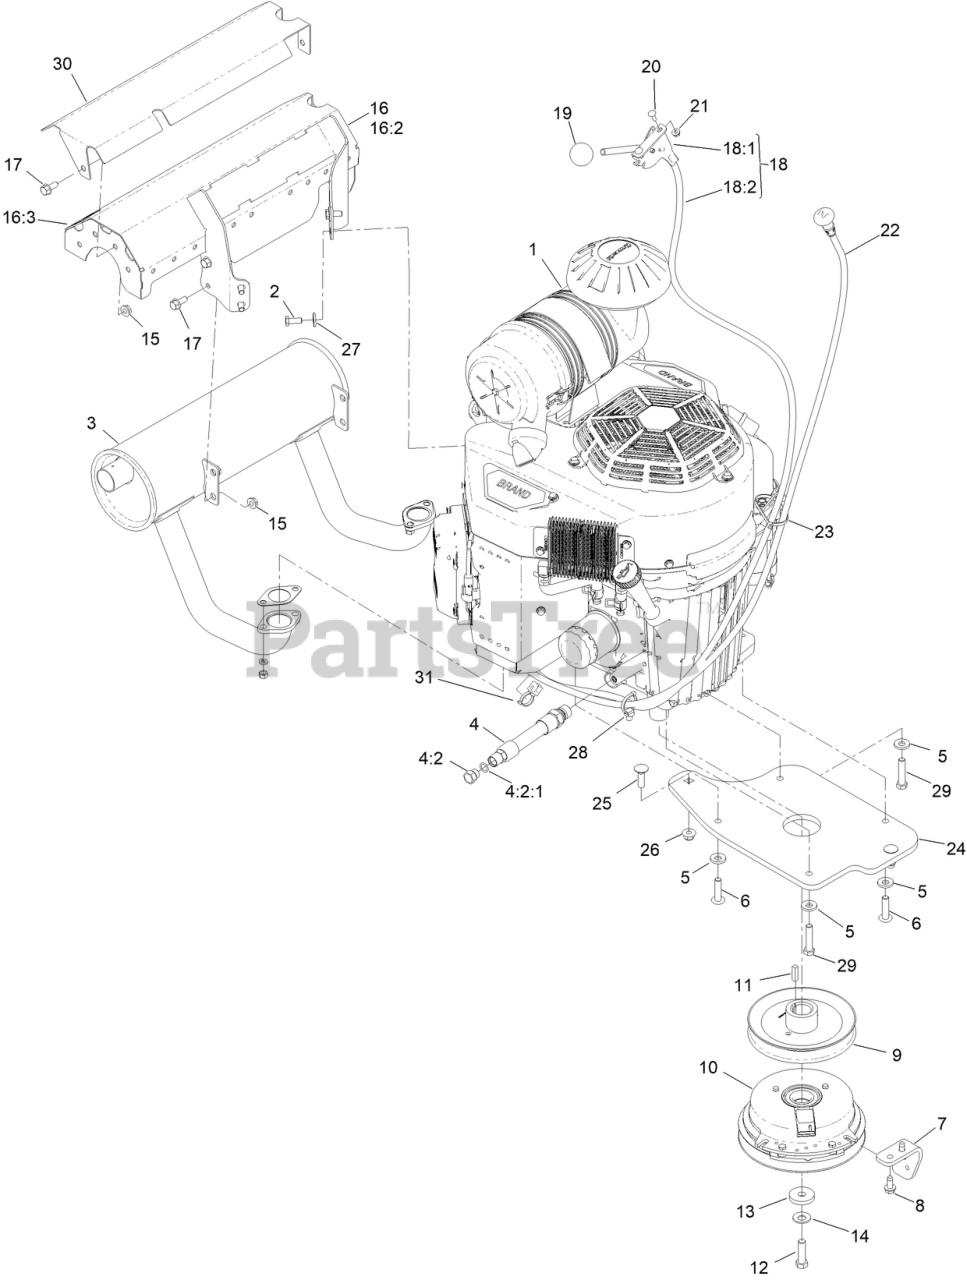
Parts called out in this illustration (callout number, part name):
2	SCREW-HH
3	MUFFLER-KAWI
4	HOSE ASM
4:2	PLUG-HH
4:2:1	O-RING
5	WASHER-BELLEVILLE
6	SCREW-BHTF
7	STOP-CLUTCH
8	SCREW-HWHTF
9	SHEAVE, W/HUB
10	CLUTCH-200CMS
12	SCREW-HH
13	WASHER
14	WASHER-SPRING
15	NUT-HF
16	MUFFLER GUARD ASM
16:2	TAPE-HEAT, SHIELD
16:3	DECAL-WARNING
17	SCREW-HHF
18	THROTTLE ASM
18:1	LEVER-CONTROL
18:2	CABLE-THROTTLE
19	KNOB-BALL
20	BOLT-CARR
21	NUT-LOCK, FLANGE
22	CABLE-CHOKE
23	TIE-CABLE
24	PLATE-ENG SPACER
25	BOLT-CARR
26	NUT-HF, NI
27	WASHER-SPRING
28	CLIP-TIE
29	SCREW-HH
30	SHIELD-HEAT
31	CLIP-EDGE W/TIE, PERPENDICULAR
